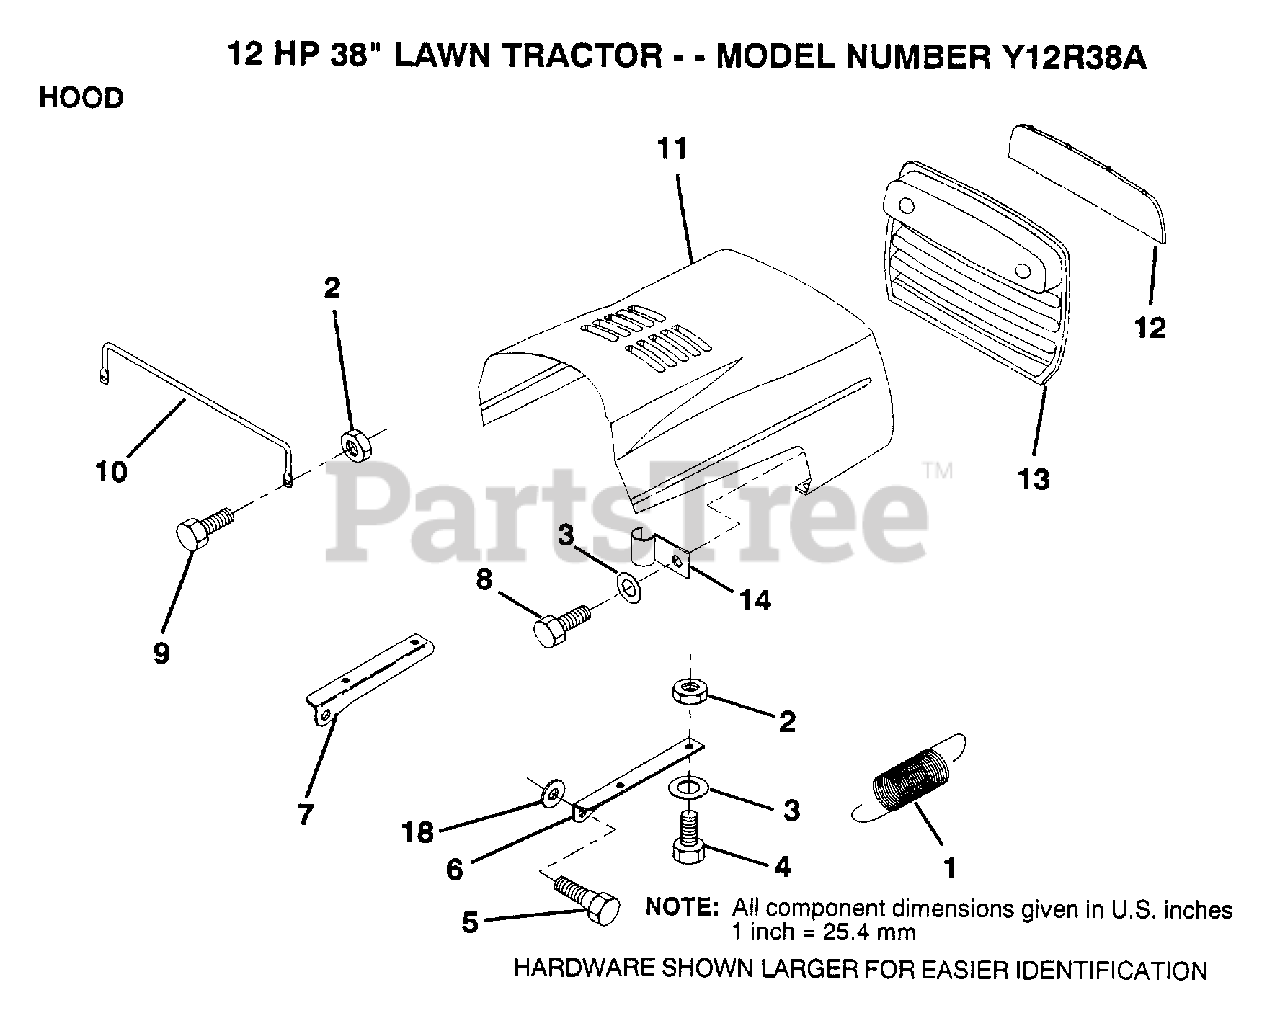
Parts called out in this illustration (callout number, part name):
1	EXT SPRING
2	NUT
3	WASHER
4	BOLT
6	BRKT HOOD RH
7	BRKT HOOD LH
10	"BRACE,HOOD"
11	HOOD
12	LENS
13	GRILL
14	CLIP T
18	WASHER
